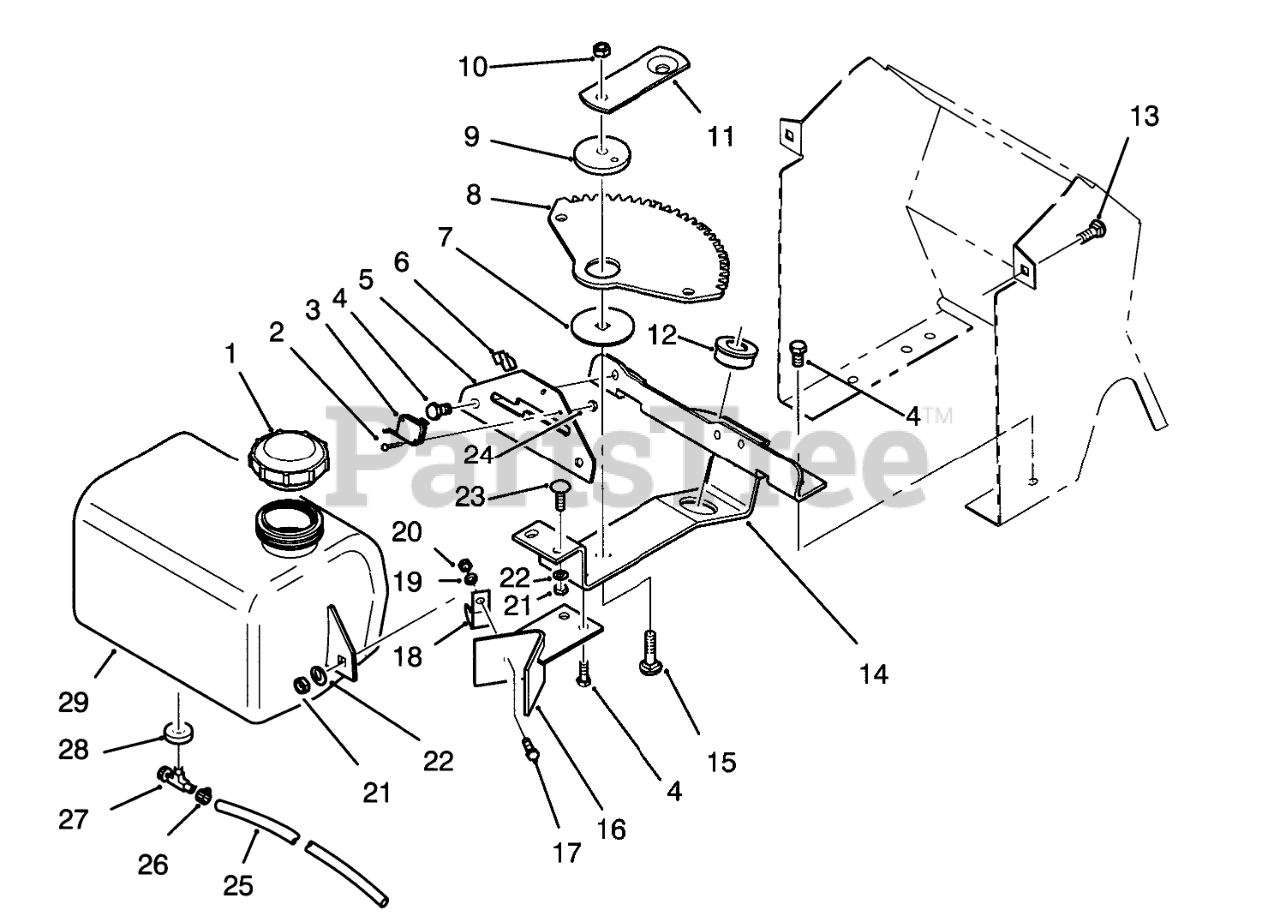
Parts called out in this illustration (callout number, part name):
1	CAP GAS
2	Screw
3	SWITCH - CLUTCH
4	HEX WASH HD SCREW
5	PLATE-SHIFT R
6	CLIP-CABLE
7	WASHER-BEARING
8	GEAR-SECTOR
9	BUSHING
11	Plate
12	BEARING-WHEEL
13	SCREW-CARR
14	STEERING BRKT - W/A R
15	BOLT-CARR
16	Stop
17	Bolt
18	CLIP
20	NUT-LOCK, NI
21	NUT-LOCK, NI
22	WASHER-PLAIN
23	Bolt-Carriage
24	NUT HEX 4-40 ELAST
25	FUEL HOSE(1 FT.6554)
26	CLAMP-HOSE
27	VALVE-FUEL
28	BUSHING
29	Tank-Fuel (Incl. Ref. #27-29)
